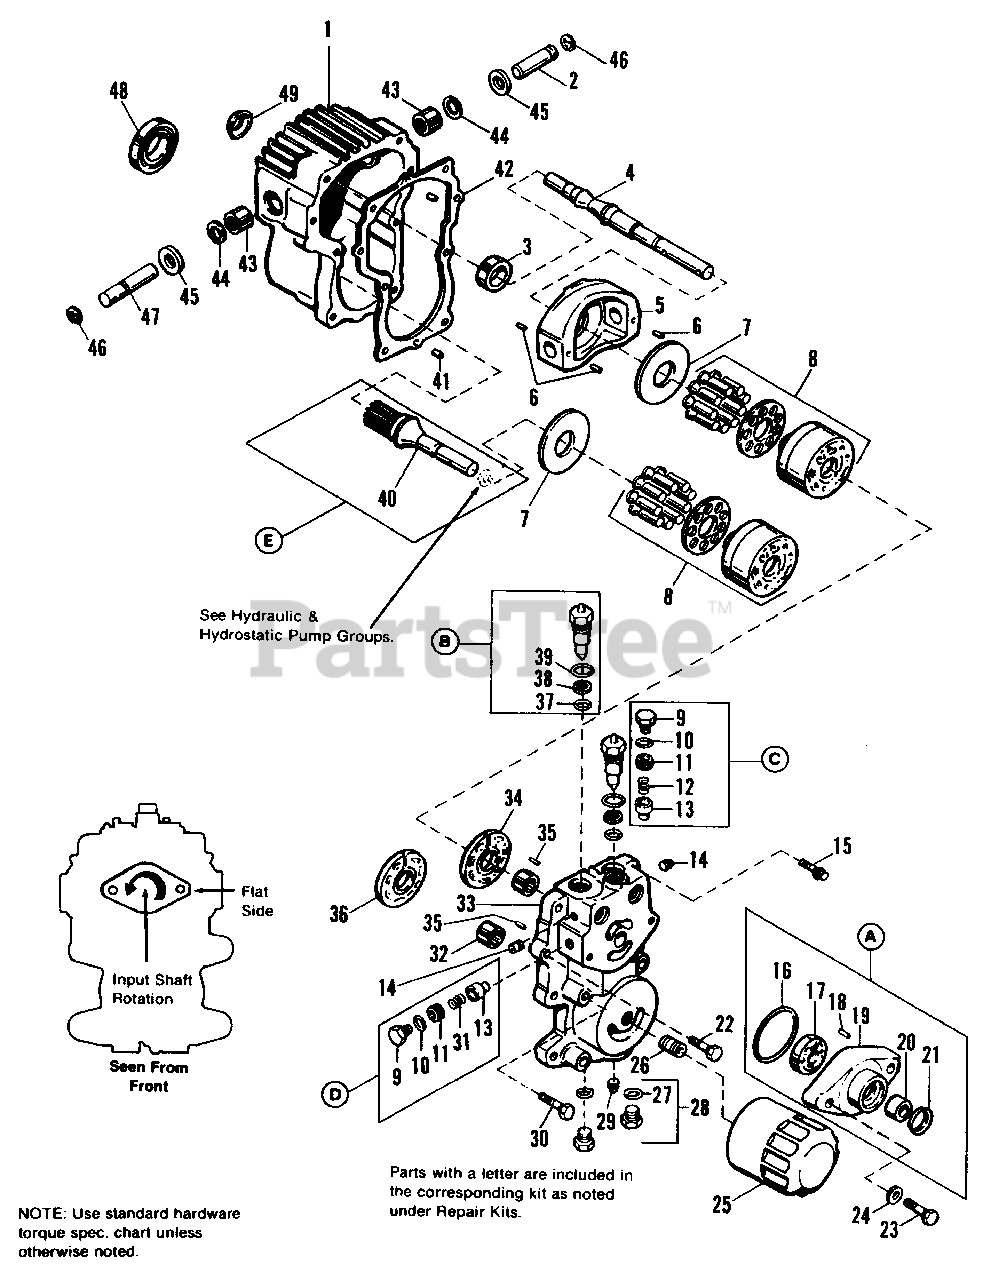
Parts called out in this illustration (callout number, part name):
1	HOUSING ASSY. (Incl. Ref. Nos. 49, 43 & 44)
2	SHAFT, Trunnion
3	BEARING, Ball
4	SHAFT, Pump
5	PLATE, Swash
6	PIN, Spring
7	PLATE, Thrust
8	BLOCK, Cylinder
9	PLUG, Hex Hd.
11	KIT, Shim Pack
12	SPRING, Rel. Valve
13	CONE, Rel. Valve
14	PLUG, Pipe
15	SCREW, 12 Pt.
18	PIN, Straight
19	HOUSING, Charge Pump
20	BEARING, Roller
22	CAPSCREW, Hex Hd., 3/6-16 x 1-1/4
23	CAPSCREW,Hex Hd., 7/16-14 x 2
24	WASHER, Flat
25	FILTER ASSY.
26	UNION, Filter
28	PLUG, Hex Hd. (Incl. Ref. No. 27)
29	PLUG, Pipe (Incl. Ref. No. 27)
30	CAPSCREW, Hex Hd., 3/8-16 x 2
31	SPRING, Rel. Valve
32	BEARING, Roller
33	SECTION, Center
34	PLATE, Valve (Pump)
35	PIN, Headless, St.
36	PLATE, Valve (Motor)
38	RING, Back-Up
40	SHAFT, Motor
41	PIN, Headless
43	BEARING, Needle
46	RING, Retaining
47	SHAFT, Trunnion
48	BEARING, Ball
A	CHARGE PUMP KIT (Incl. Ref. Nos. 16, 17, 18, 19, 20 & 21)
B	CHECK VALVE ASSY. (Incl. Ref. Nos. 37, 38 & 39)
C	RELIEF VALVE KIT (Incl. Ref. Nos. 9, 10, 11, 12 & 13)
D	RELIEF VALVE KIT (Incl. Ref. Nos. 9, 10, 11, 13 & 31)
E	SHAFT & SNAP RING KIT
